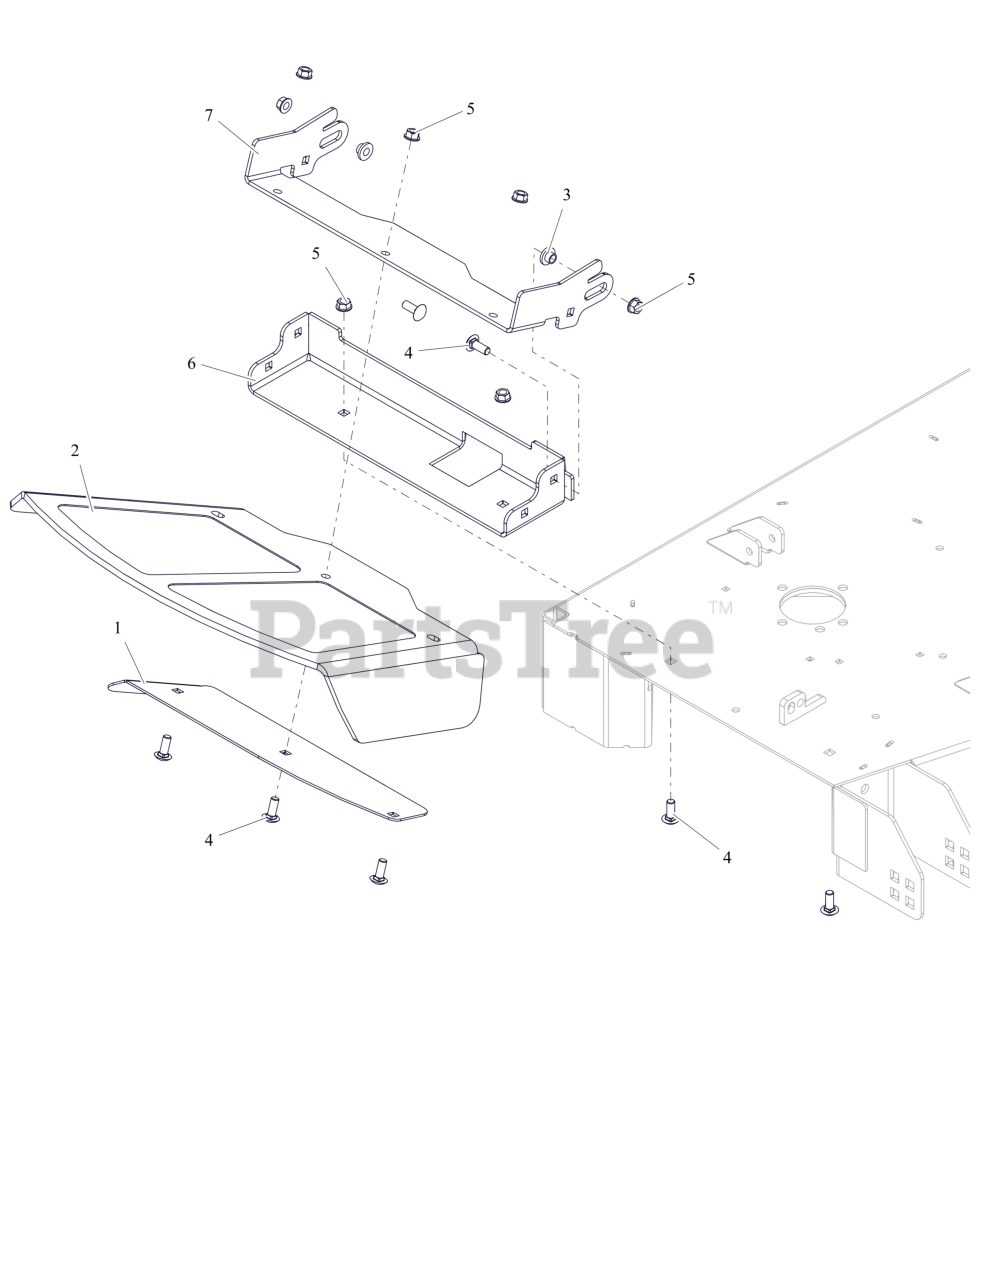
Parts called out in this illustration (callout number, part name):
1	48-60 DISCH CHUTE CLMP PLT-RED
2	CHUTE, FORMED RUBBER DISCHARGE
3	BSHG-FLG .385X.500X.875X.406
4	BLT,RHSSN .38-16X1.00 G5 ZCC
5	NUT-LK-CTR-FLG .375-16 GF ZCC
6	BASE, 48" DISCHARGE CHUTE MTG BRKT (RED)
7	BRKT- CHUTE MTG
